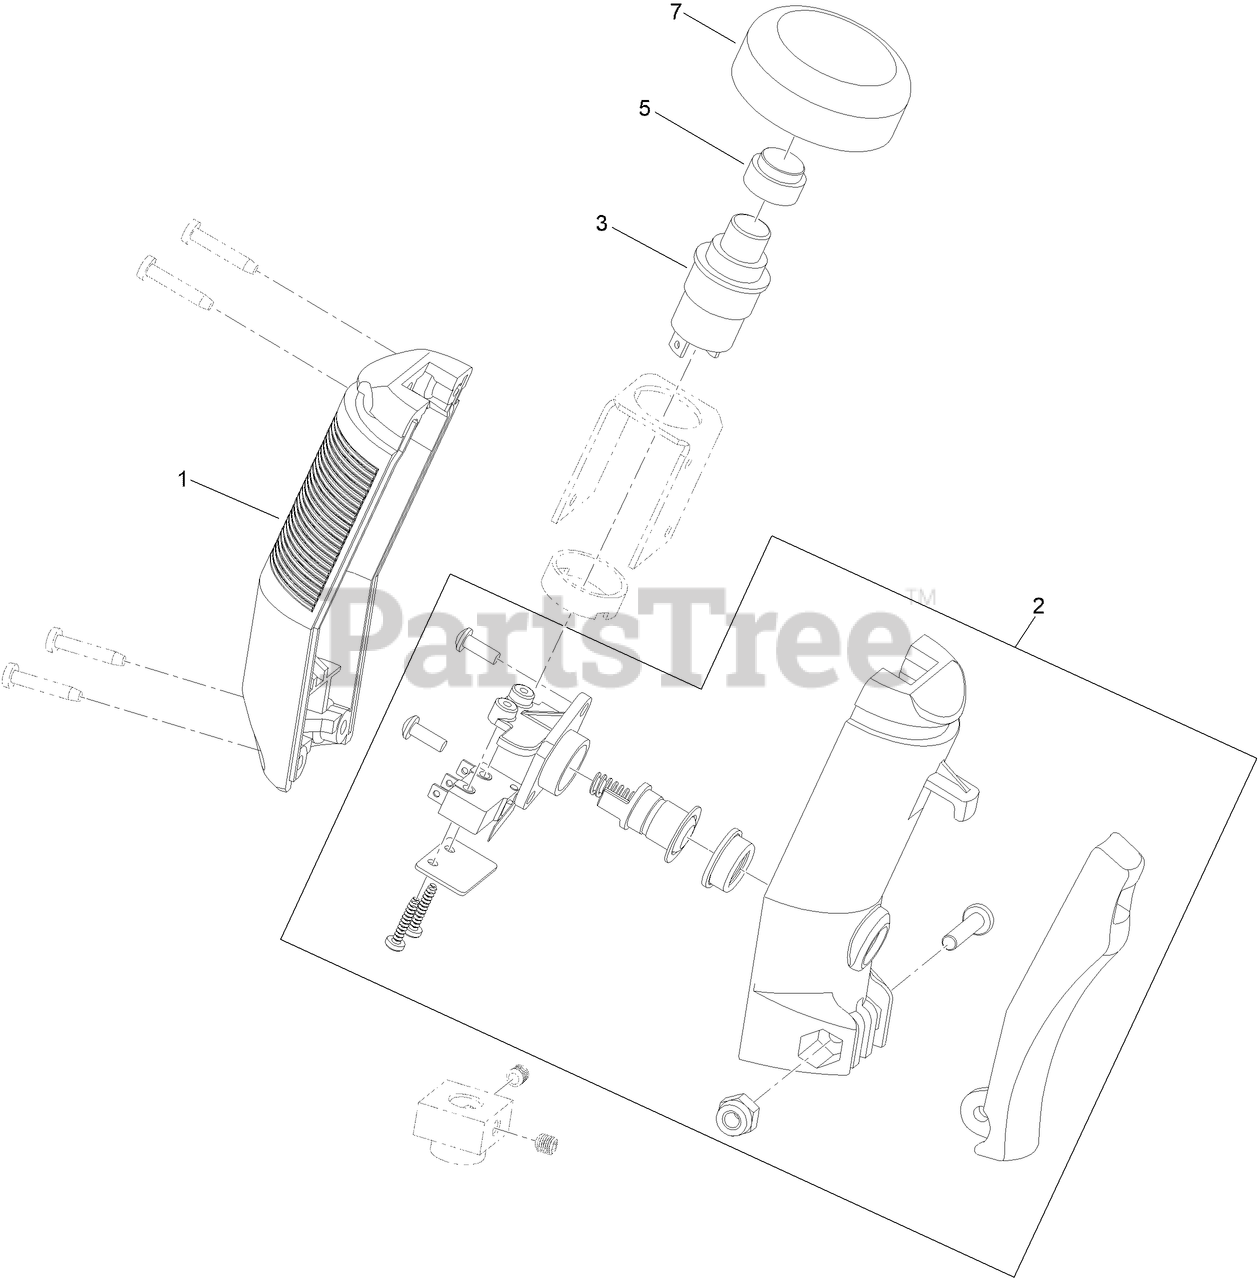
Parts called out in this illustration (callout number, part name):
1	HALVE-HANDLE
2	SWTICH KIT
3	BUTTON-PUSH, TOP
5	BUTTON-ACTUATOR
7	BOOT-BUTTON
